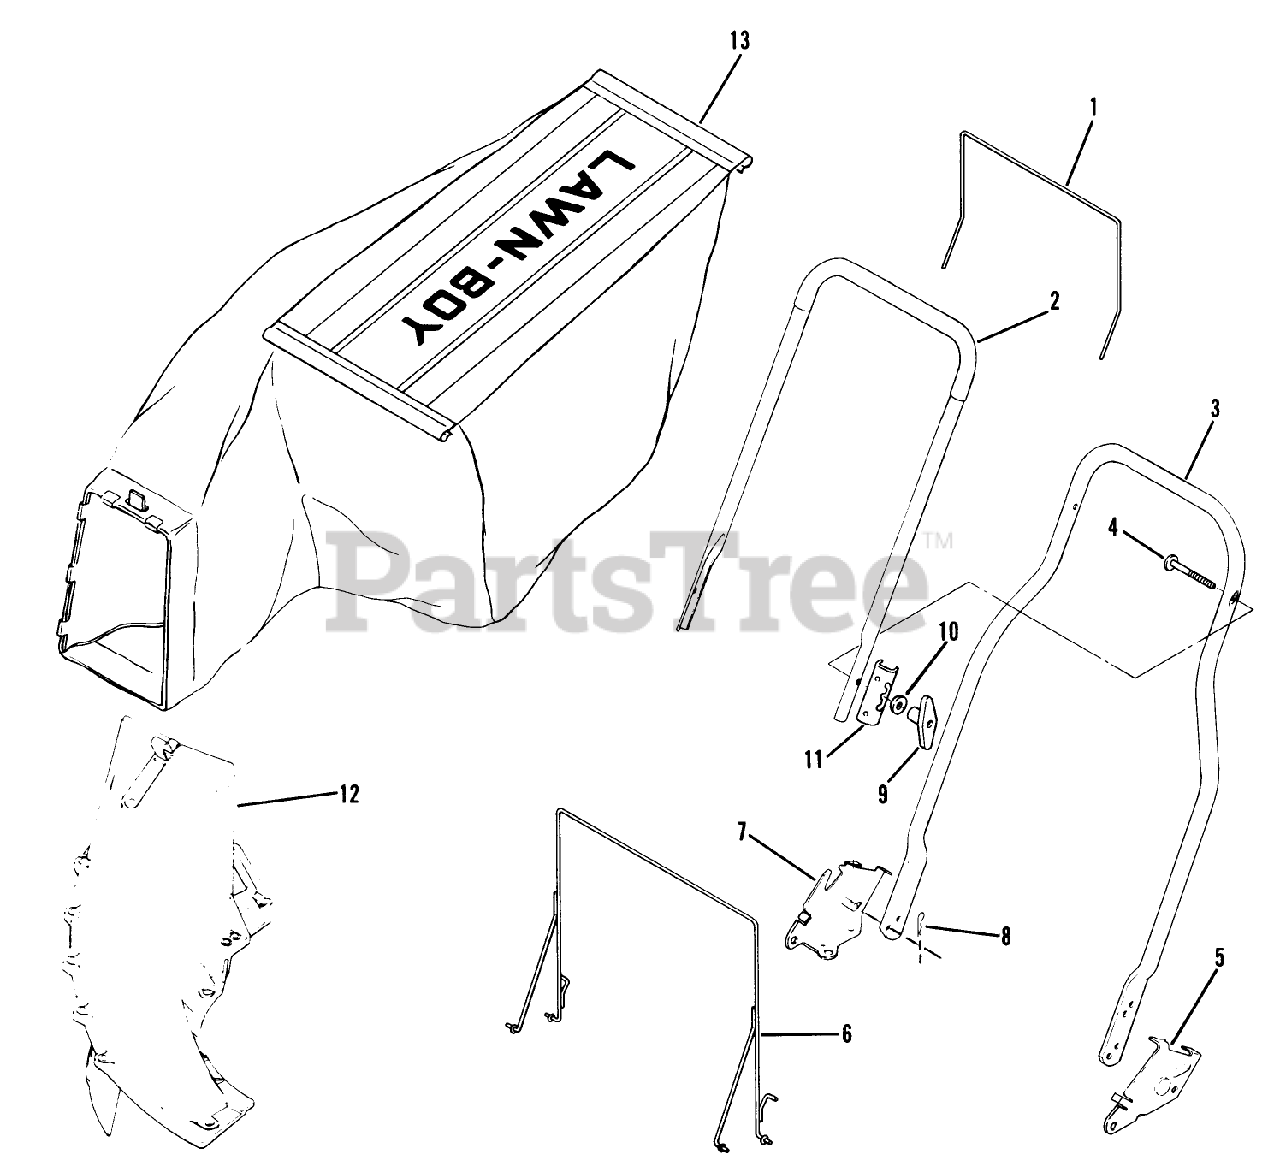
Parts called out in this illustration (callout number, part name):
1	HANGER
8	HAIR PIN
9	NUT-WING
10	WASHER-CURVED
11	BRACKET R/B 613462
